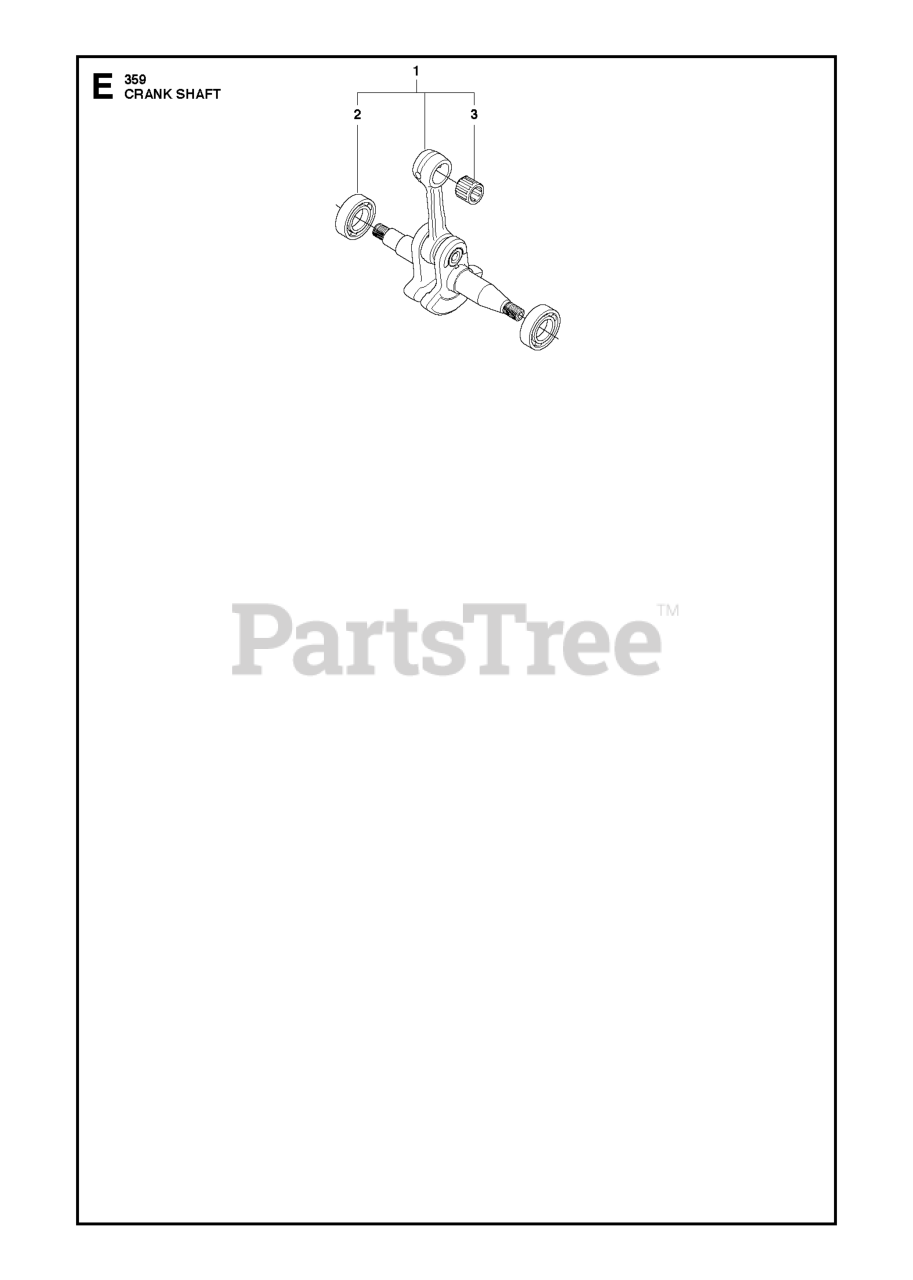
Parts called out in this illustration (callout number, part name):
1	RP CRANKSHAFT
2	BALL BEARING-6202-C3 SKF
3	SUPPORT BUSHING
